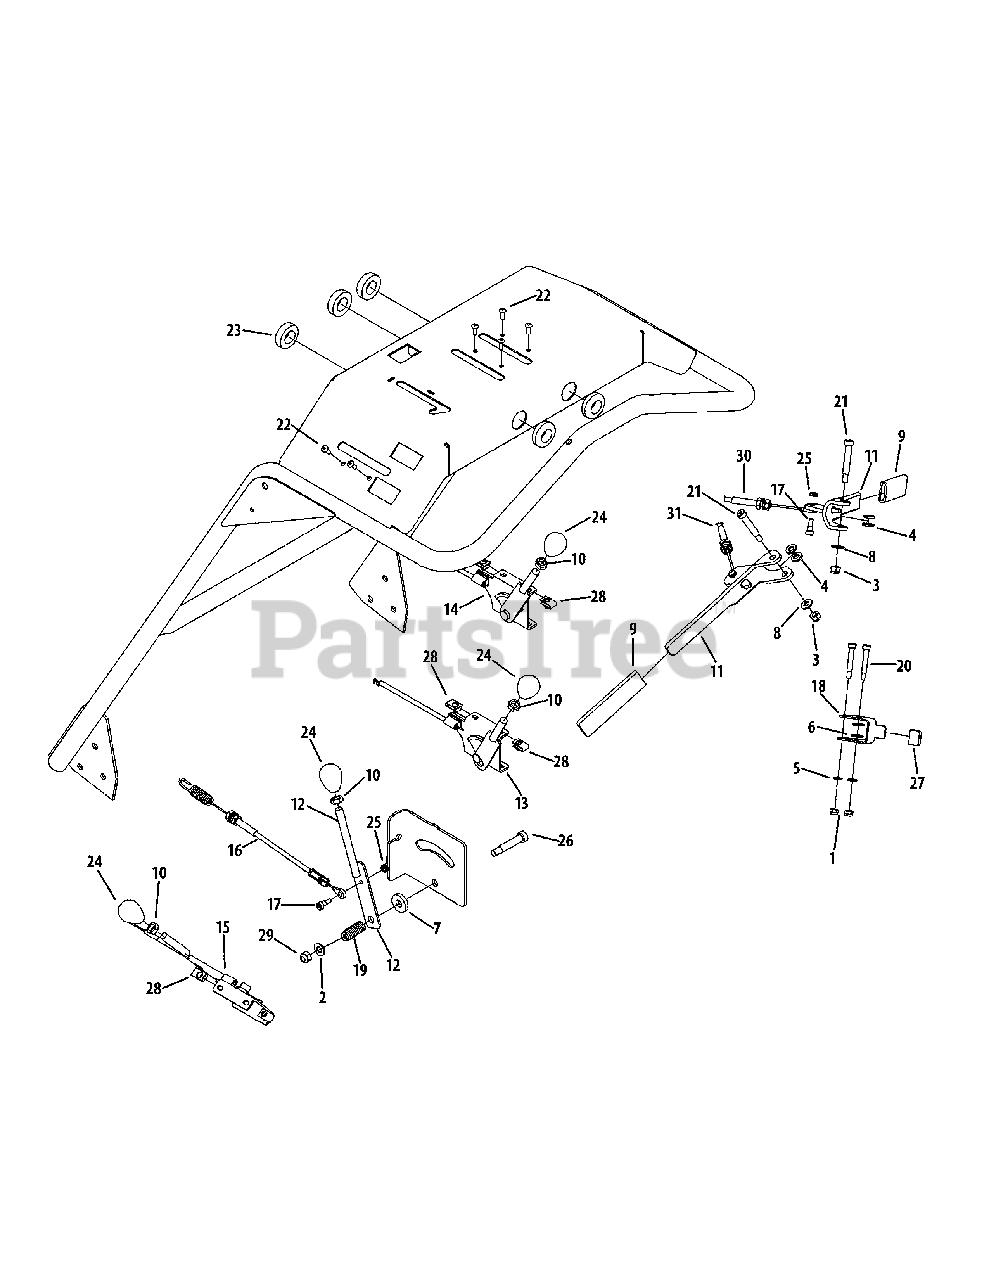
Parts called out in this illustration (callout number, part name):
1	Nut, #10-24
2	Flat Washer, 5/16
3	Nut, 1/4-20
4	Flat Washer, 5/16
5	Flat Washer, 3/16
6	Flat Washer, 1/4
7	Flat Washer, .390 x 1.0 x .180
8	Flat Washer, 1/4 x .630 x .0515
9	Control Sleeve
10	Nut, 3/8-16
12	On/Off Lever
13	3rd-Hole Control
14	Remote Deflector Cable
15	Throttle Control
16	On/Off Cable
17	Shoulder Bolt, 1/4 x 1/4
18	Speed Control Lever
19	Compression Spring, .625 x .390 x 1.2
20	Shoulder Bolt, 1/4 x 1-1/4
21	Shoulder Bolt, 5/16 x 1-1/2
22	Hex Screw, 10-24 x 1/2
23	Rubber Grommet, .750 x 1.375 x .1
24	Lever Knob, 3/8-16
25	Washer Nut, 10-24
26	Shoulder Bolt, 3/8 x 1-1/2
27	Speed Control Lever Sleeve
28	Nut, 10-24
29	Hex Lock Nut, 5/16-18
30	Forward Control Cable, 74.25
31	Reverse Control Cable, 94.25
